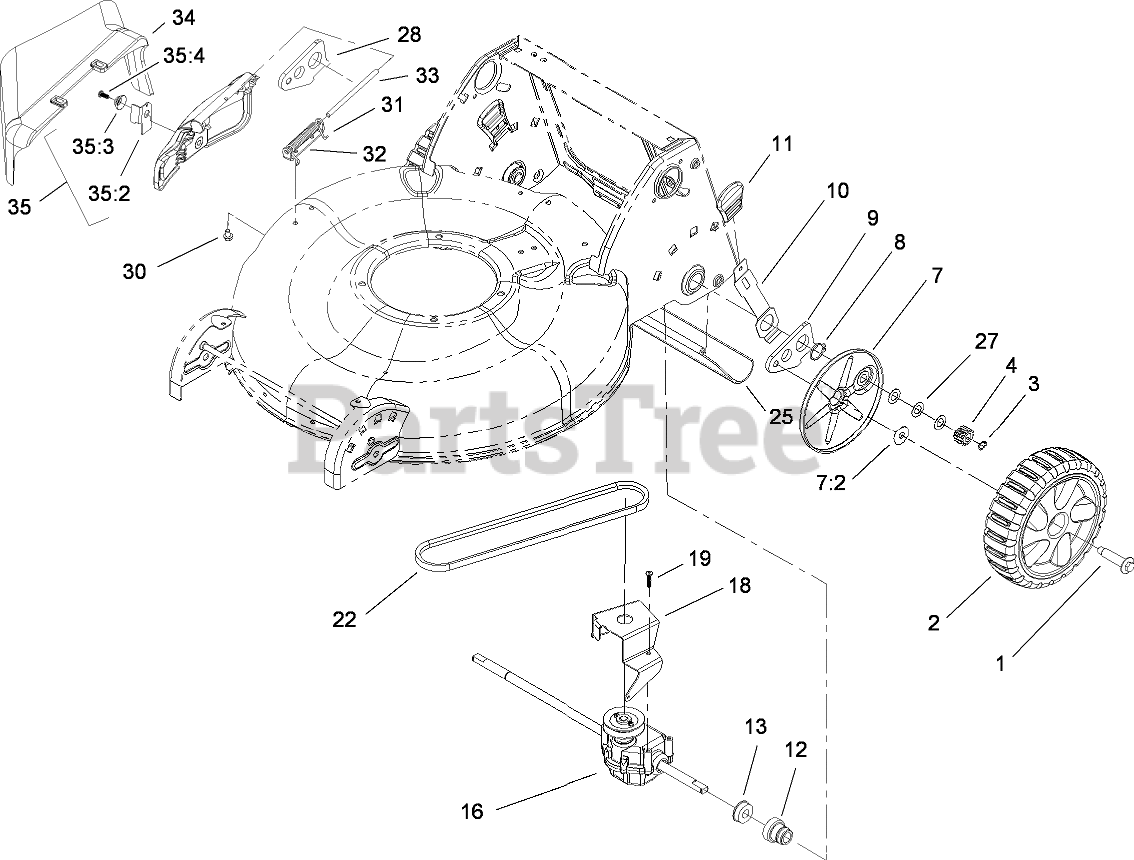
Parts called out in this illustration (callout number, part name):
1	BOLT-SHOULDER
2	REAR WHEEL ASM
3	RING-RETAINING
4	GEAR-PINION, 15T
7	WHEEL COVER ASM
7:2	WASHER-STEPPED
8	RING-RETAINING
9	ARM-REAR PIVOT, LH
10	ARM-SPRING, REAR
11	KNOB-HOC
12	RETAINER-BEARING, HOC
13	BEARING-BALL
16	TRANSMISSION ASM
18	BRACKET-TRANSMISSION
19	SCREW-PLASTITE
22	V-BELT
25	SHIELD-TRAILING
27	WASHER-PLAIN
28	ARM-REAR PIVOT, RH
30	SCREW-HWH
31	SPRING-TORSION
32	BRACKET-COVER
33	ROD-COVER
34	CHUTE-DISCHARGE, SIDE
35	DISCHARGE DOOR ASM
35:2	LATCH-DOOR
35:3	CAP-DOOR
35:4	SCREW-PLASTITE
